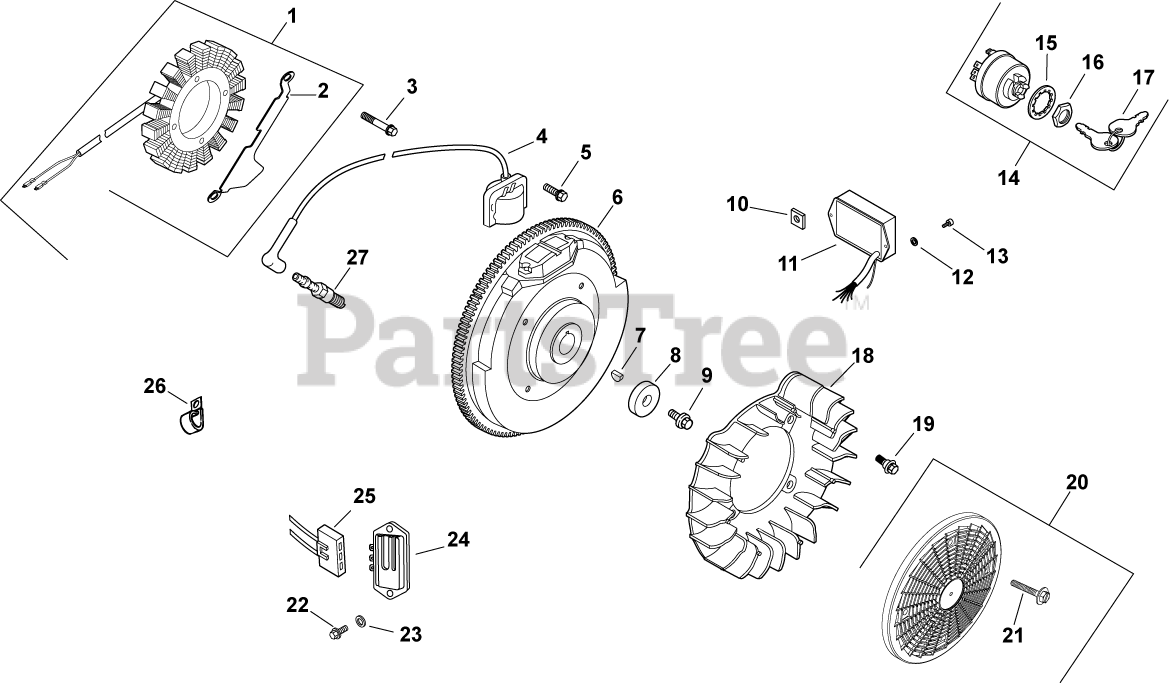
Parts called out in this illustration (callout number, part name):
1	STATOR KIT - USE 237878-S
2	BRACKET, GROUND STRAP USE 24 518 12-S
3	SCREW, M5X0.8X25 - (#25086402S)
4	MODULE, IGNITION
5	SCREW, FLG THD FRM M5X.8X20-(#25086399S)
6	FLYWHEEL ASSEMBLY-USE 24 025 58-S
7	KEY, 3/16" X 5/8"
8	WASHER, FLAT 13/32"
9	SCREW, FLG M10X1.5X45 - (#25086361S)
10	NUT, PLASTIC
11	MODULE, SPEED ADVANCE -USE 24 755 172-S
12	WASHER, FLAT 1/4" (O.D. 1/2")
13	SCREW, PHL HD #11-16X1/2"
14	SWITCH ASSY, KEY (KM)-USE 25 099 32-S
15	WASHER, INTERNAL TOOTH
16	NUT, KEY SWITCH
17	KEY, SET OF 2
18	FAN USE 24 755 253-S
19	BOLT, SHOULDER
20	KIT, GRASS SCREEN
21	SCREW, FLG SEMS M4X.7X25
22	SCREW, PHL HD #11-16X7/8"
23	WASHER, FLAT 3/16"
24	REG/RECT-15 AMP (KM)-USE 41 403 10-S
25	CONNECTOR, BODY (KM)-USE 25 155 41-S
26	CLIP, CABLE
27	PLUG, SPARK (PRO SERIES)
2458452-S	MODULE, SPARK ADV -USE 24 584 89-S
